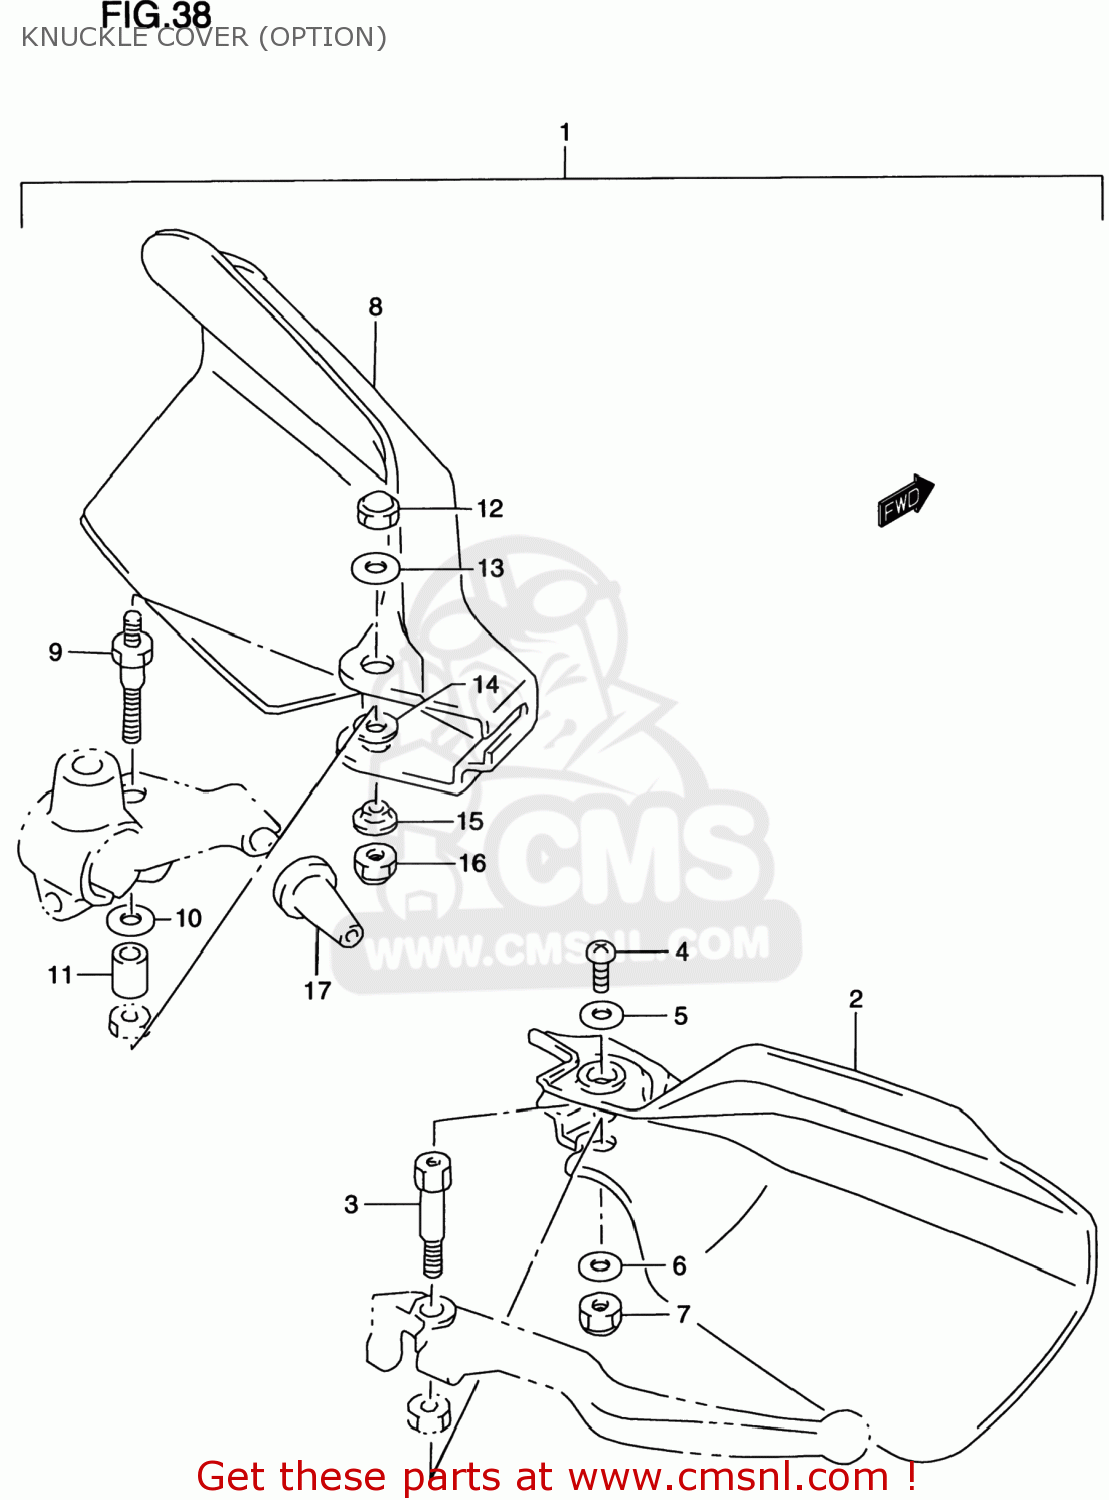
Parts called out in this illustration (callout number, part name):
1	COVER SET,KNUCKLE
2	COVER,KNUCKLE,R
3	BOLT,BRAKE LEVER PIVOT
4	SCREW
5	WASHER(5.5X16X1.2)
6	WASHER(6.5X16X1.6)
7	NUT 6MM
8	COVER,KNUCKLE,LEFT
9	BOLT,LEVER SET
10	WASHER,LEVER SET
11	SPACER,LEVER SET
12	NUT
13	WASHER(6.5X20X1.6)
14	WASHER(6.5X16X1.2)
15	WASHER
16	NUT 6MM
17	BOOT,CLUTCH CABLE
